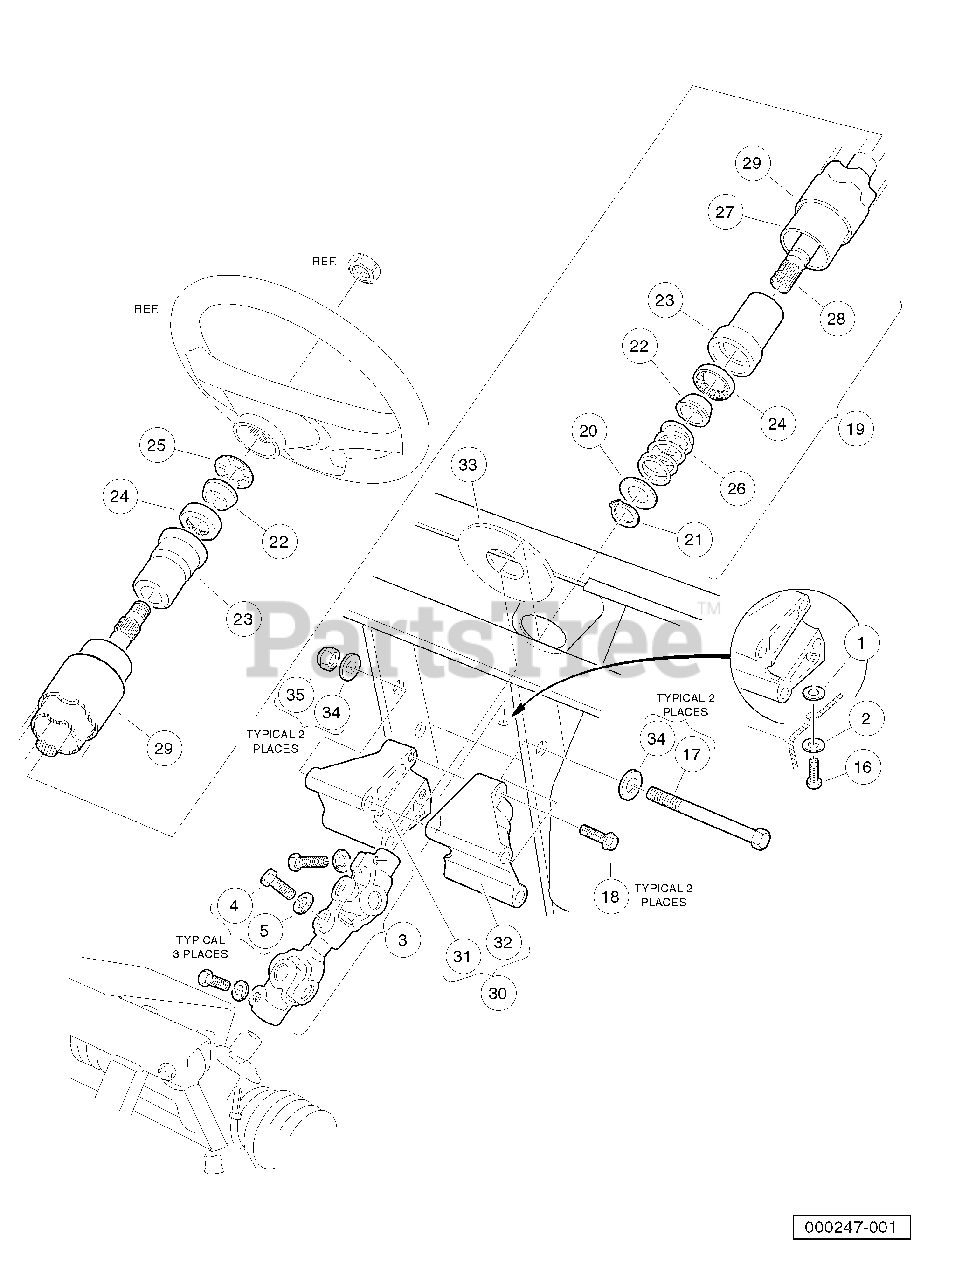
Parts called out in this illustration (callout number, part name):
1	Washer, 5/16 Type B Flat
2	Washer, 5/16 Flat
3	Intermediate Steering Shaft
4	Bolt, Hex-Head, 8mm X 1.25 - 30
5	Lockwasher, 5/16 Split
7	Dust Cover
8	Ring, 0.579 Internal Retaining
9	Wedge, Molded
10	Seat, Plastic Bearing
11	Seal, Bearing
12	Spacer, Shaft
13	Bearing, Ball
14	Ring, Retaining
15	Spring, Steering Shaft
16	Screw, 5/16-18 X 0.75 Thread-Forming
17	Screw, 3/8-16 X 7.00 Hex Cap
18	Screw, 5/16-18 Thrd Forming
19	Steering Shaft Assembly
20	Washer, 0.675 ID X 1.19 OD
21	Ring, 0.579 Internal Retaining
22	Wedge, Molded
23	Seat, Plastic Bearing
24	Bearing, Ball
25	Ring, Retaining
26	Spring, Steering Shaft
27	Column, Aluminum Steering
28	Shaft Steering Column
29	Tube Cover, Steering Column
30	Kit, Steering Column Mounting Bracket
31	Bracket, RH Steering Column Mount
32	Bracket, LH Steering column mount
33	Boot, Steering Column Round
34	Washer, 3/8 Type A Flat
35	Locknut, 3/8-16 Hex
